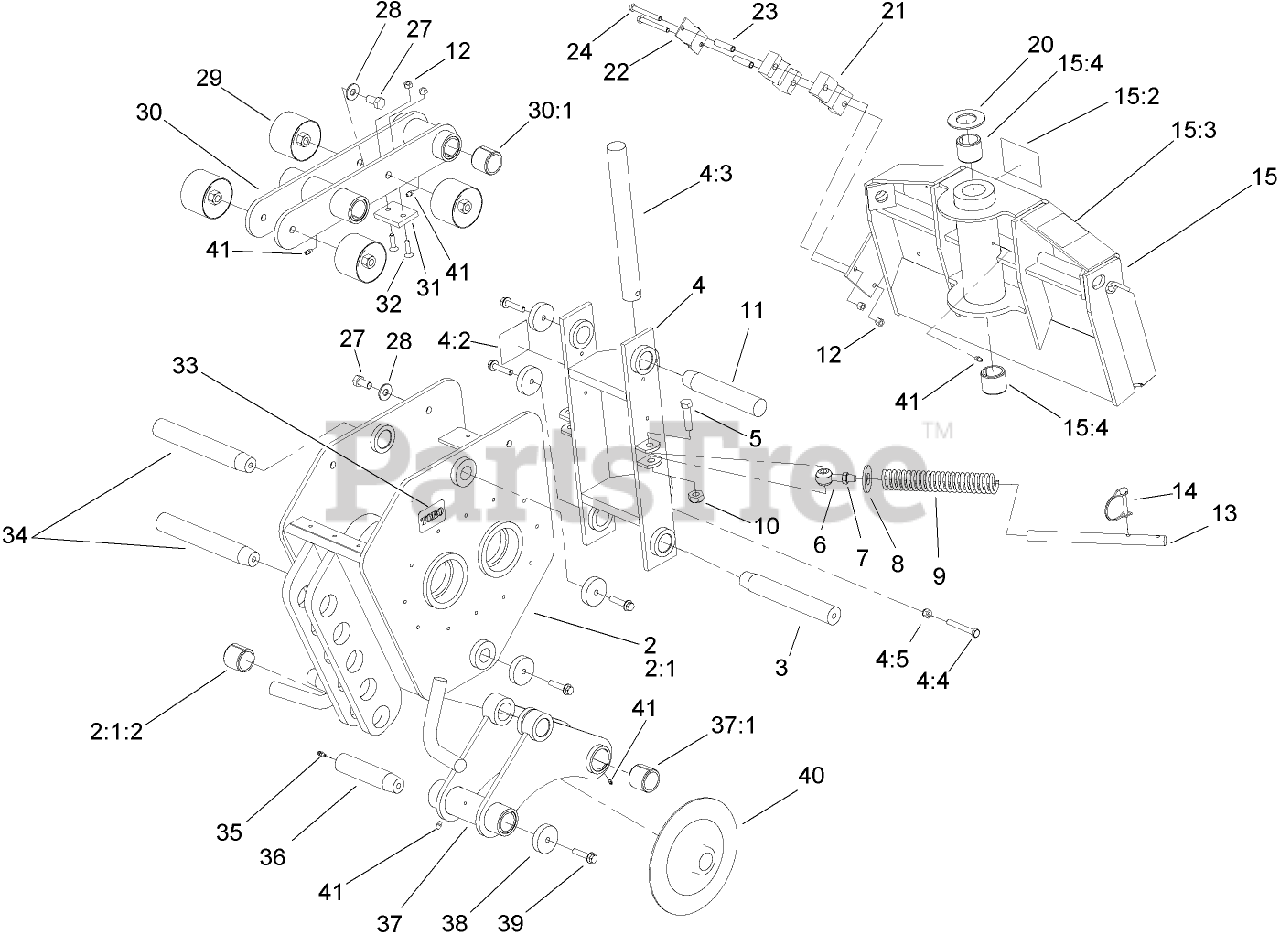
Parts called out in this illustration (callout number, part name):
2	FRAME ASM
2:1	FRAME ASM
2:1:2	BUSHING-TENSION
3	PIN-TAPERED
4	CLEVIS ASM
4:2	DECAL-WARNING
4:3	PIN-PIVOT
4:4	SCREW-HH
4:5	NUT-LOCK, NI
5	SCREW-HH
6	ROD END
7	NUT-JAM
8	WASHER
10	NUT-HEX
11	PIN-TAPERED
12	NUT-LOCK, NI
13	ROD-THREADED
14	PIN-HITCH
15	Q-TACH ASM
15:2	DECAL
15:3	DECAL-DANGER
15:4	BUSHING-TENSION
20	WASHER
21	CLAMP
22	SPACER
23	CLAMP-DRAIN, CASE
24	SCREW-HH
27	SCREW-HH
28	WASHER-FLAT
29	MOUNT-SANDWICH
30	LINK ASM
30:1	BUSHING-TENSION
31	PAD-STOP
33	DECAL
34	PIN-TAPERED
35	FITTING-GREASE
36	PIN-TAPERED
37	LINK ASM
37:1	BUSHING-TENSION
38	WASHER-CLUTCH
39	SCREW-HHF
40	COULTER
41	FITTING-GREASE, 90 DEG
